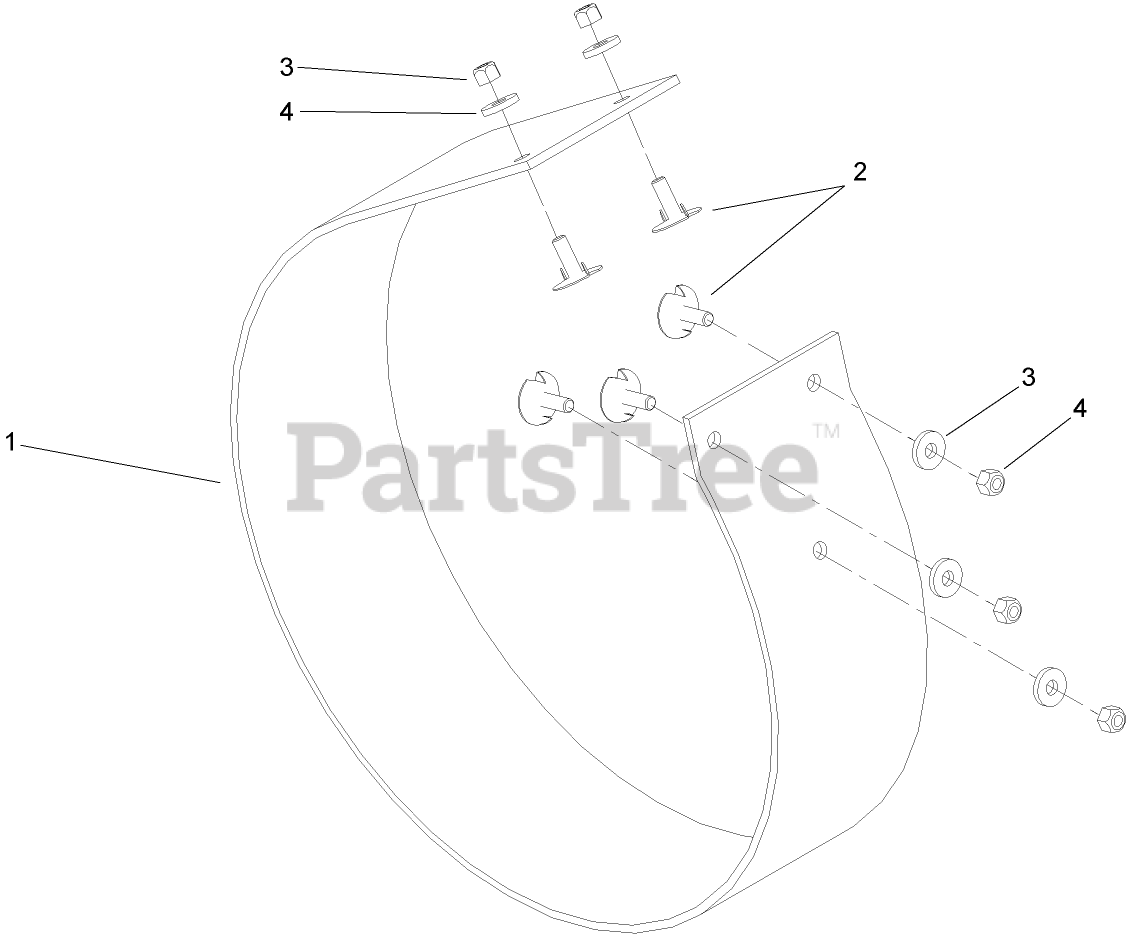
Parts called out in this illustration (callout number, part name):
1	STRIP-WEAR 4.5"
1	STRIP-WEAR 6.5"
2	BOLT-ELEVATOR, FANGED
3	WASHER-FLAT
4	NUT-LOCK, NI
